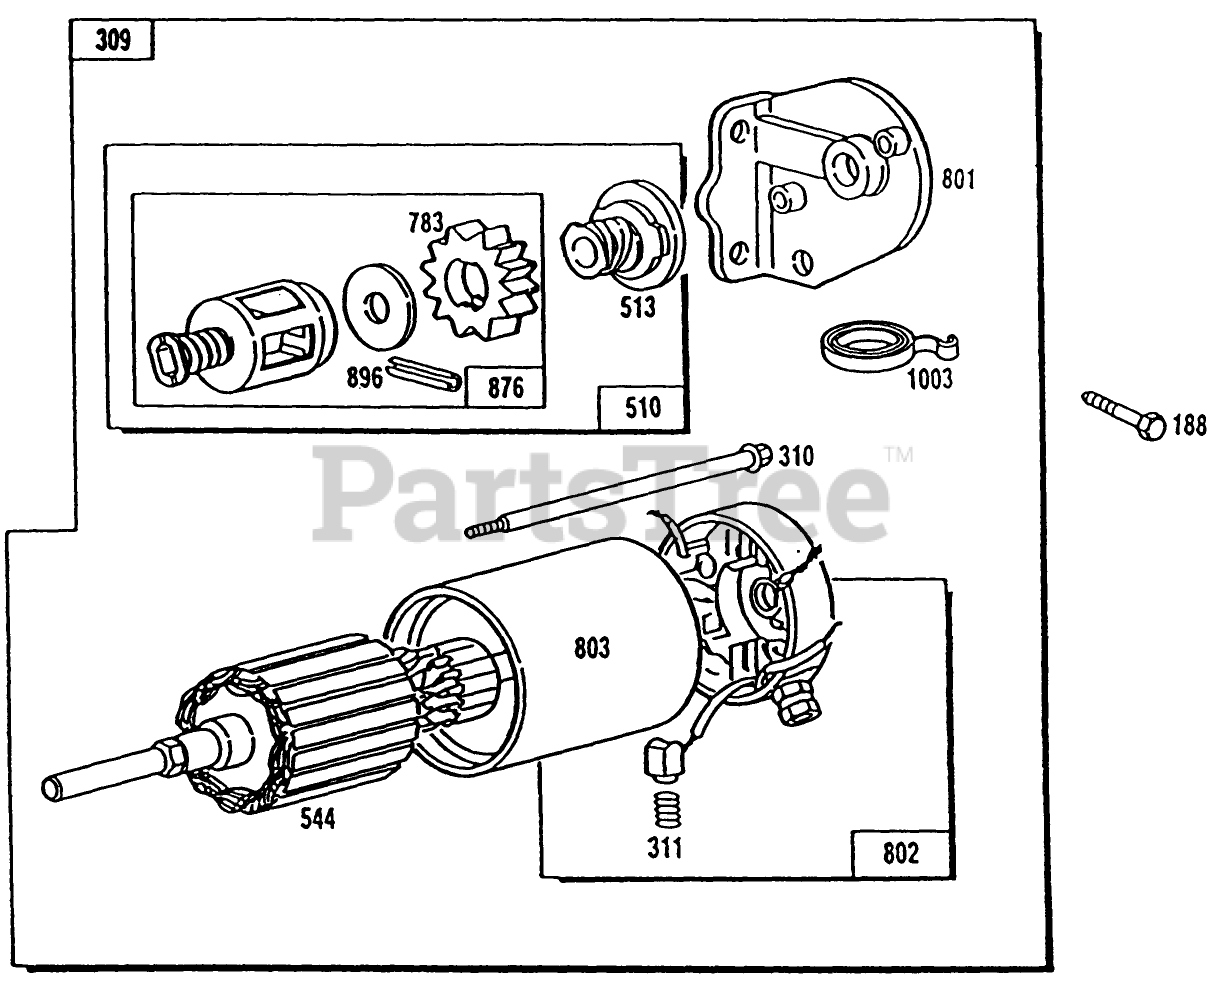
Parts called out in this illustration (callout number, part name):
188	BRIGGS-805247
310	BRIGGS-94169
311	BRIGGS-490311
513	BRIGGS-398003
801	BRIGGS-394857
803	BRIGGS-399172
876	BRIGGS-490467
896	BRIGGS 94288
1003	BRIGGS-805025
